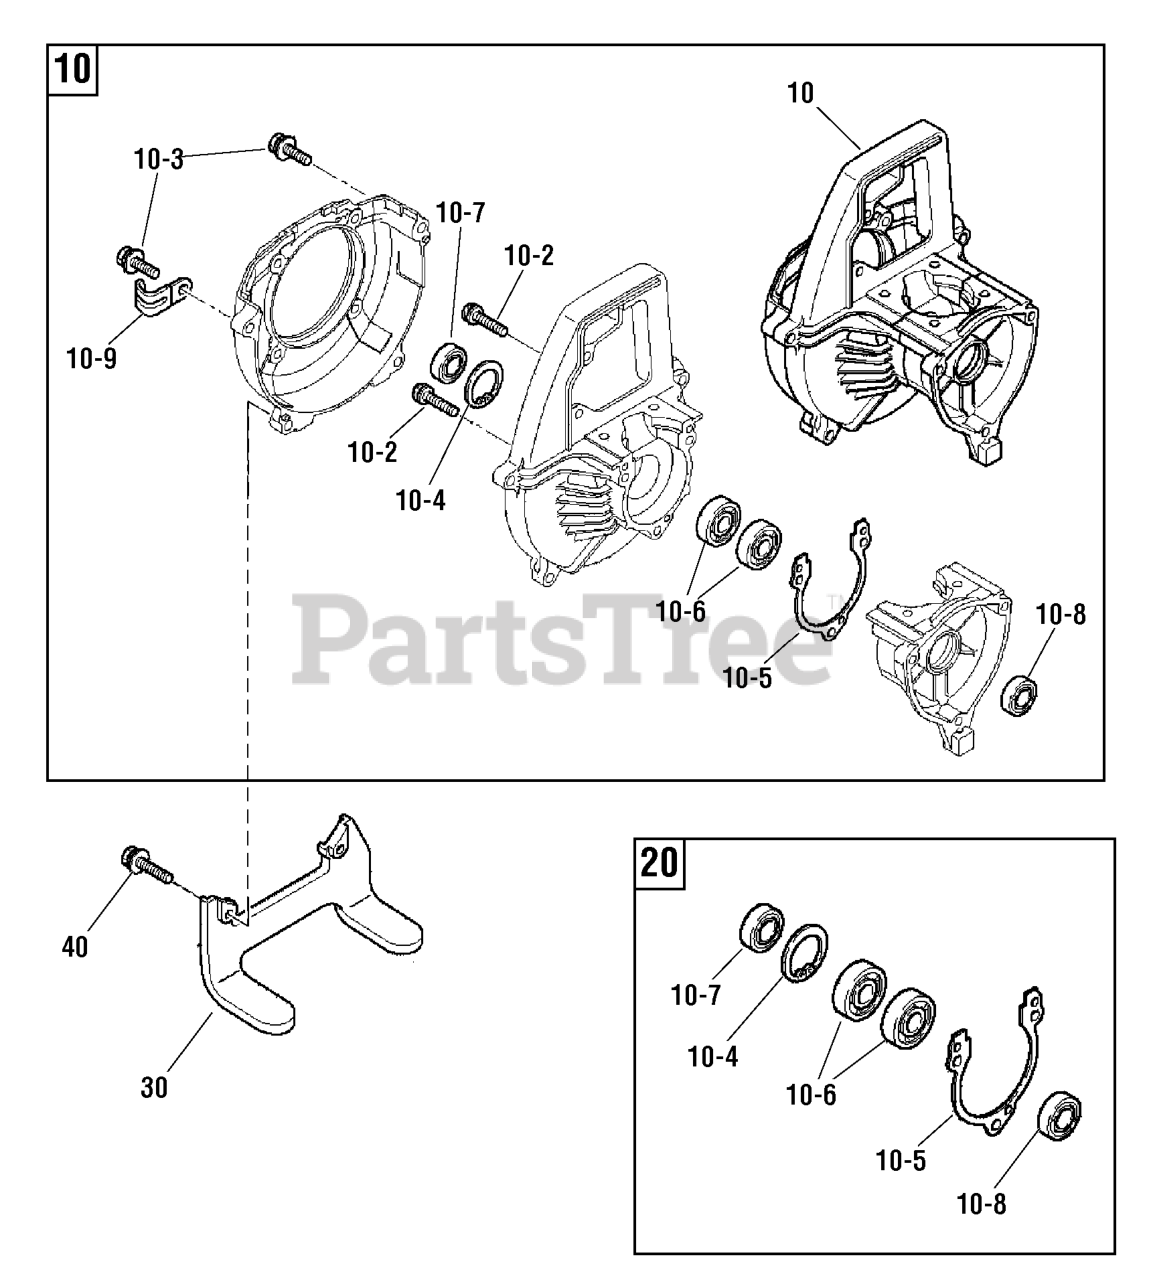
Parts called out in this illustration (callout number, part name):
10	CRANKCASE ASSEMBLY
10-2	SCREW & WASHER
10-3	BOLT & WASHER
10-4	SNAP RING
10-5	GASKET, Crankcase
10-6	BEARING, Ball
10-7	OIL SEAL
10-8	OIL SEAL
10-9	CLAMP
20	KIT, Bearing Seal & Gasket
30	ENGINE STAND
40	BOLT & WASHER
